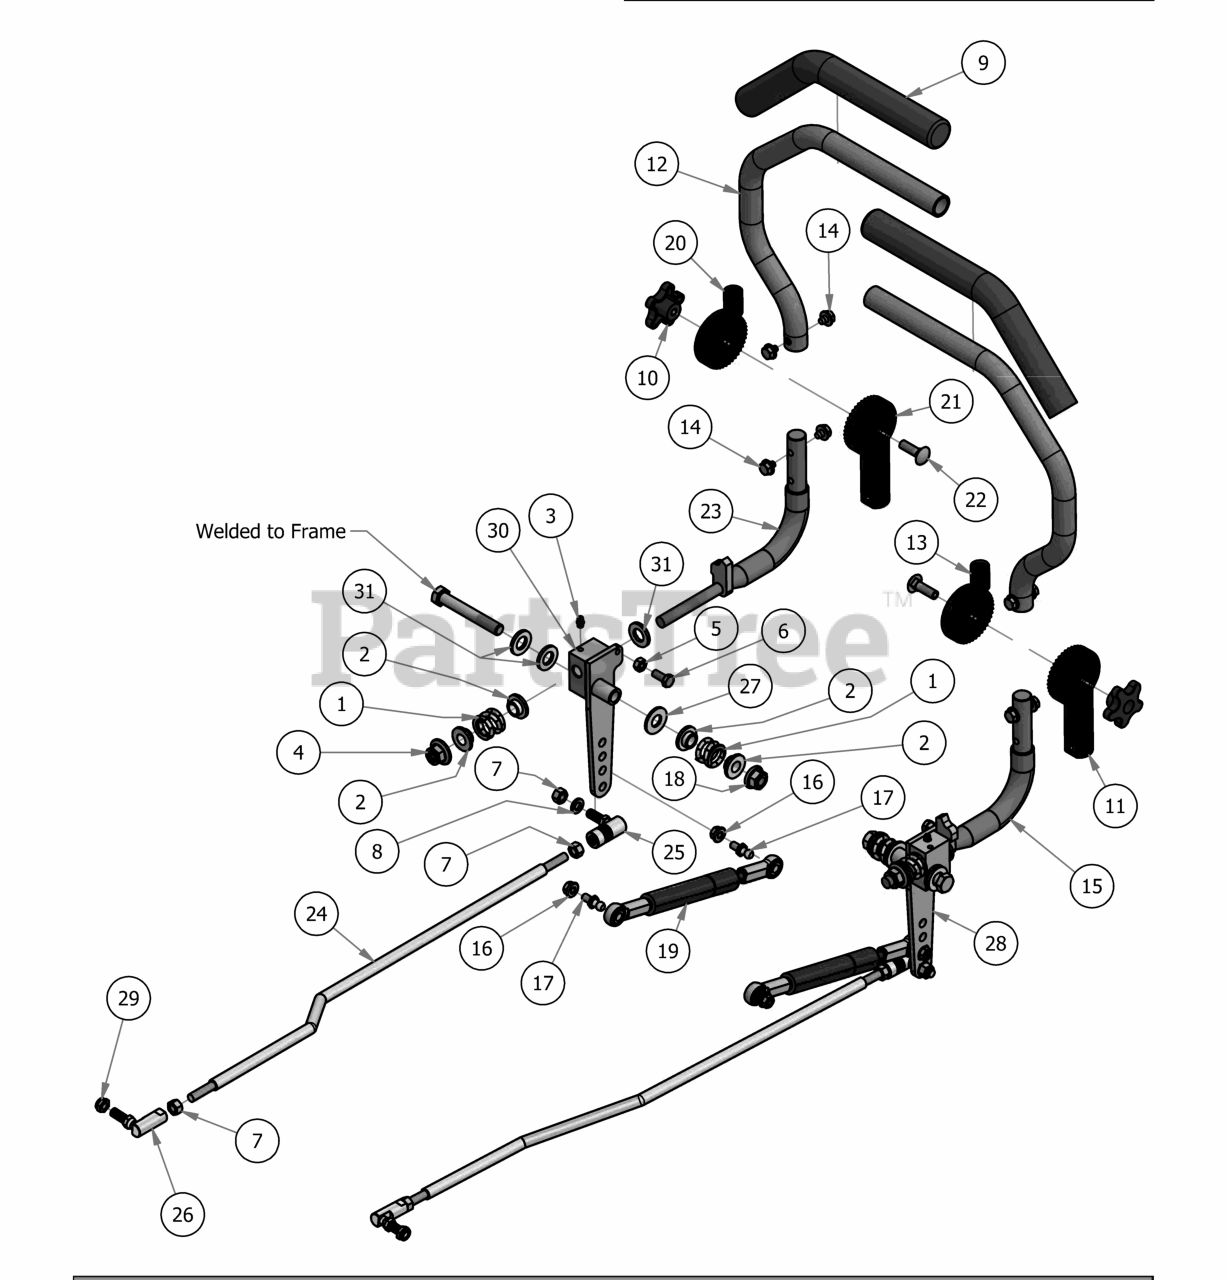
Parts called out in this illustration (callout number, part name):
1	Drive Lever Spring
2	.515 ID Nylon Shoulder Washer
3	1/4" Press in Grease Fitting
4	1/2-13 Nylon Flange Nut
6	5/16" x 3/4" Hex Bolt
7	3/8" Fine Threaded Jam Nut
8	3/8" Lock Washer
9	Black Steering Grip
10	Black Knob for Adjustable Steering Arm
11	Lower Adjuster - Steering Arm- Right
12	Upper Tube-Adjustable Steering
13	Upper Adjust Steering Arm- Right
14	5/16-18 1/2 HWH Bolt-Steering
15	Stering Arm Elbow (Right)
16	5/16" Flange Nut
17	10mm Damper Ball Stud-Steering
18	1/2-13 Hex Flange (GR.G) ZC
19	Steering Damper
20	Upper adjuster-Steering Arm- Left
21	Lower Adjuster - Steering Arm- Left
22	3/8" x 1 1/4" Carriage Bolt
23	Stering Arm Elbow (Left)
24	outlaw XP Push Rod
25	Quick Release Ball Joint
26	3/8-24 Ball Joint
27	1/2" Washer (Grade 8)
28	Steering Block Assembly - Right
29	3/8-24 Nylon Insert jam locknut
30	Steering Block Assembly - Left
31	.630 ID Plastic Washer
